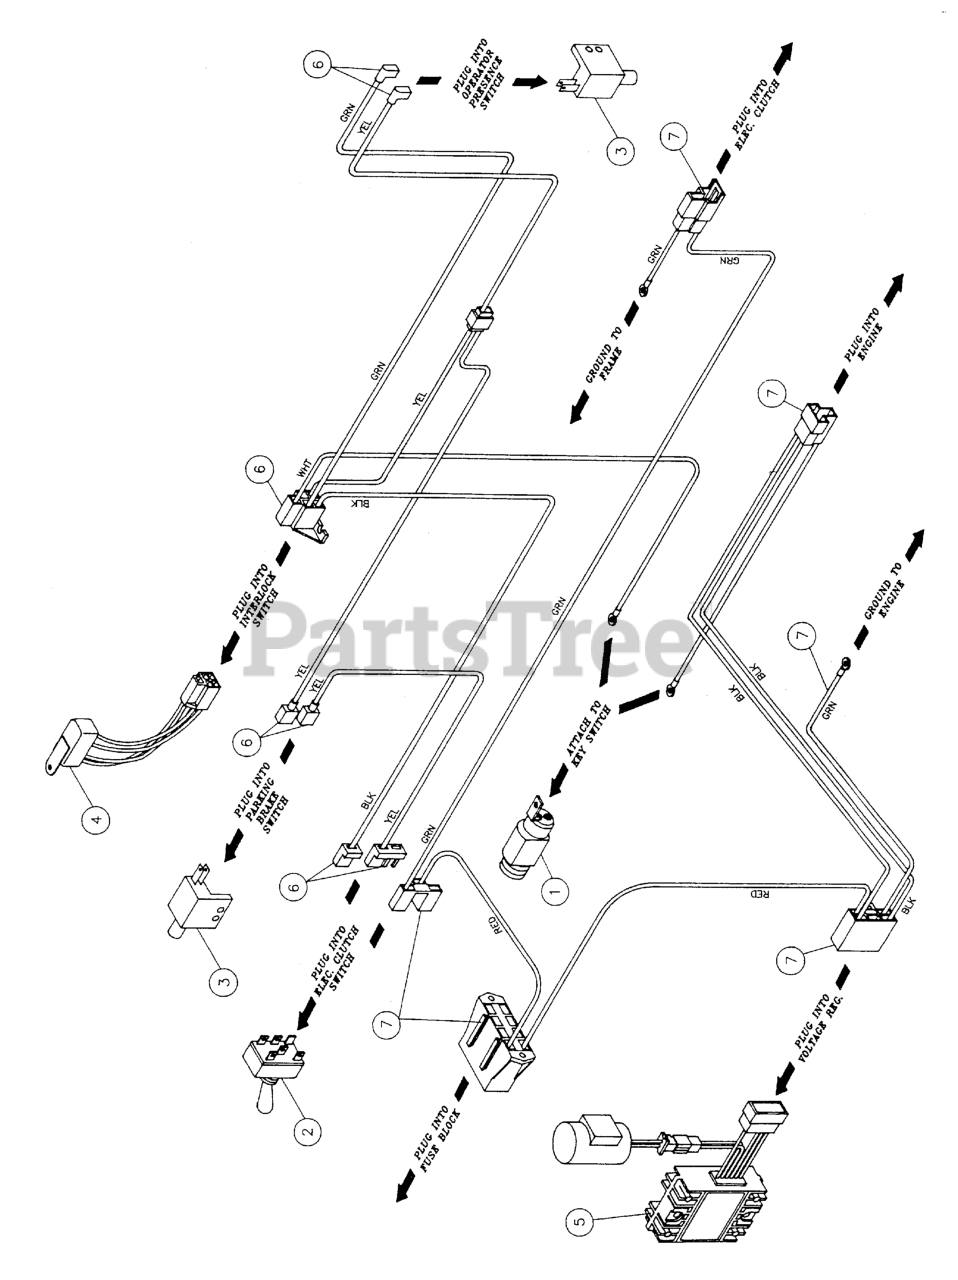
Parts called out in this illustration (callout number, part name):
1	SWITCH, Ignition
2	SWITCH, Electric Clutch
3	SWITCH, Plunger, NO
4	Saftey Interlock
6	Interlock Electrical Harness
7	Fuse Block Electrical Harness
